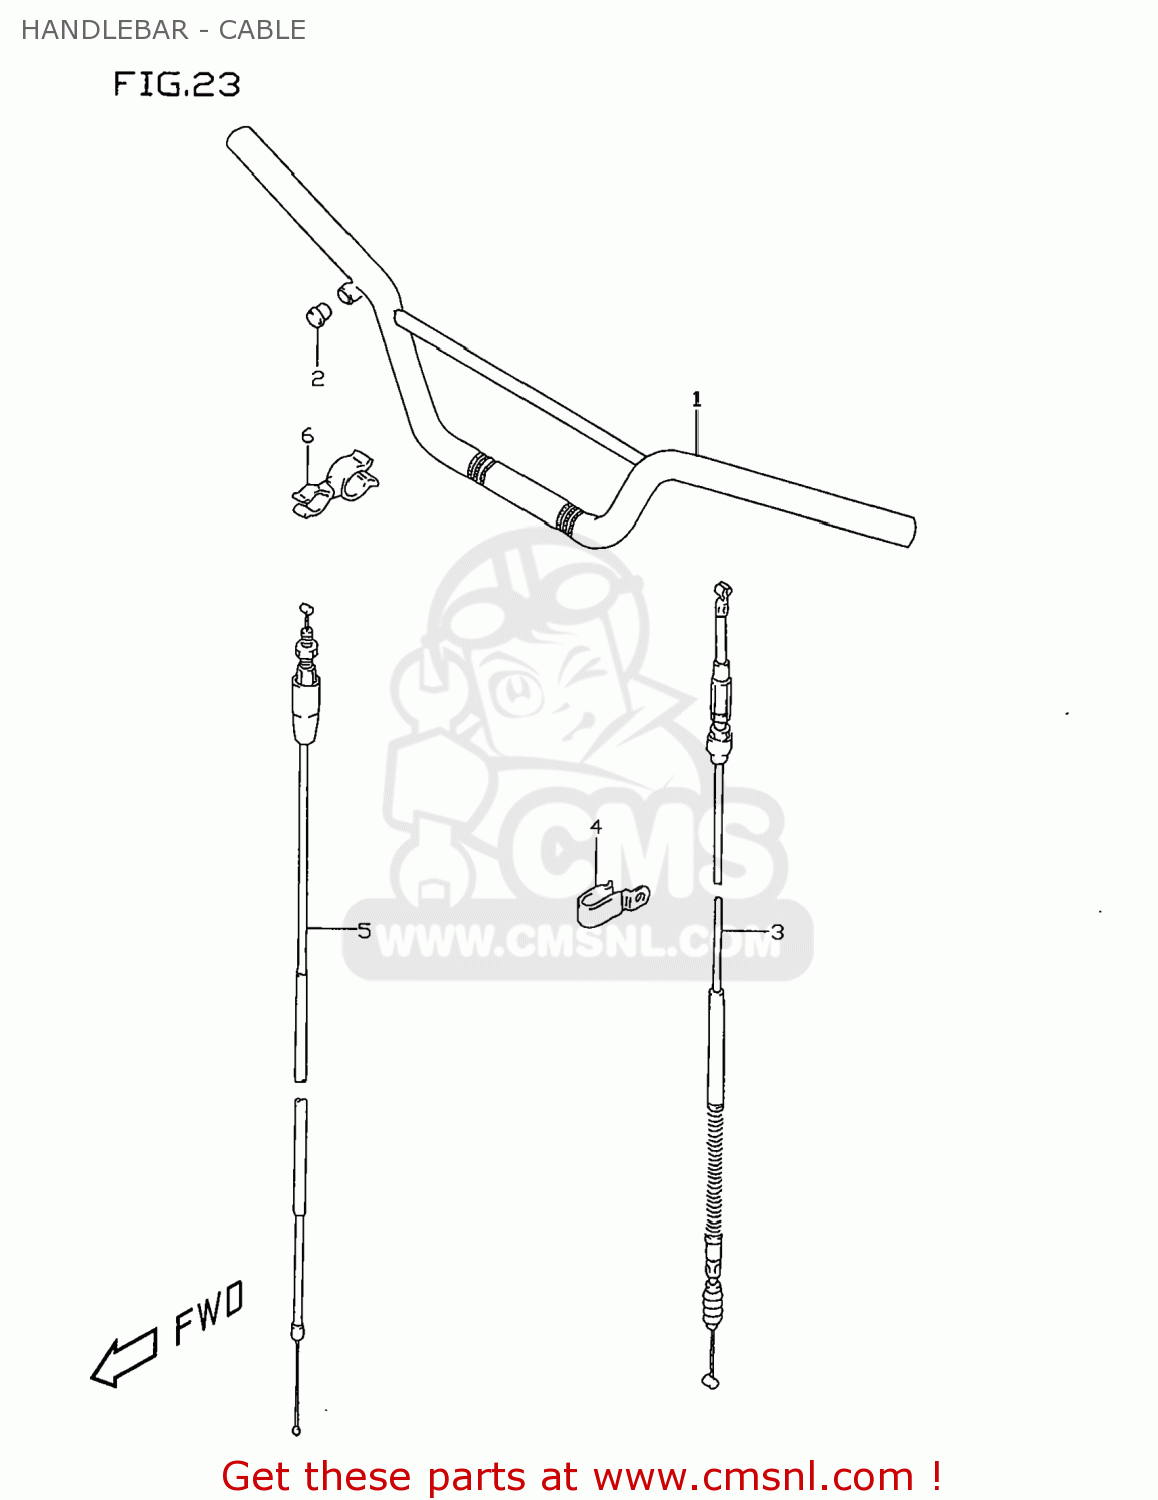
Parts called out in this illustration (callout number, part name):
1	HANDLEBAR COMP
2	CAP(OD:14)
3	CABLE ASSY,CLUTCH
4	CLAMP
5	CABLE ASSY,THROTTLE
6	CLAMP
